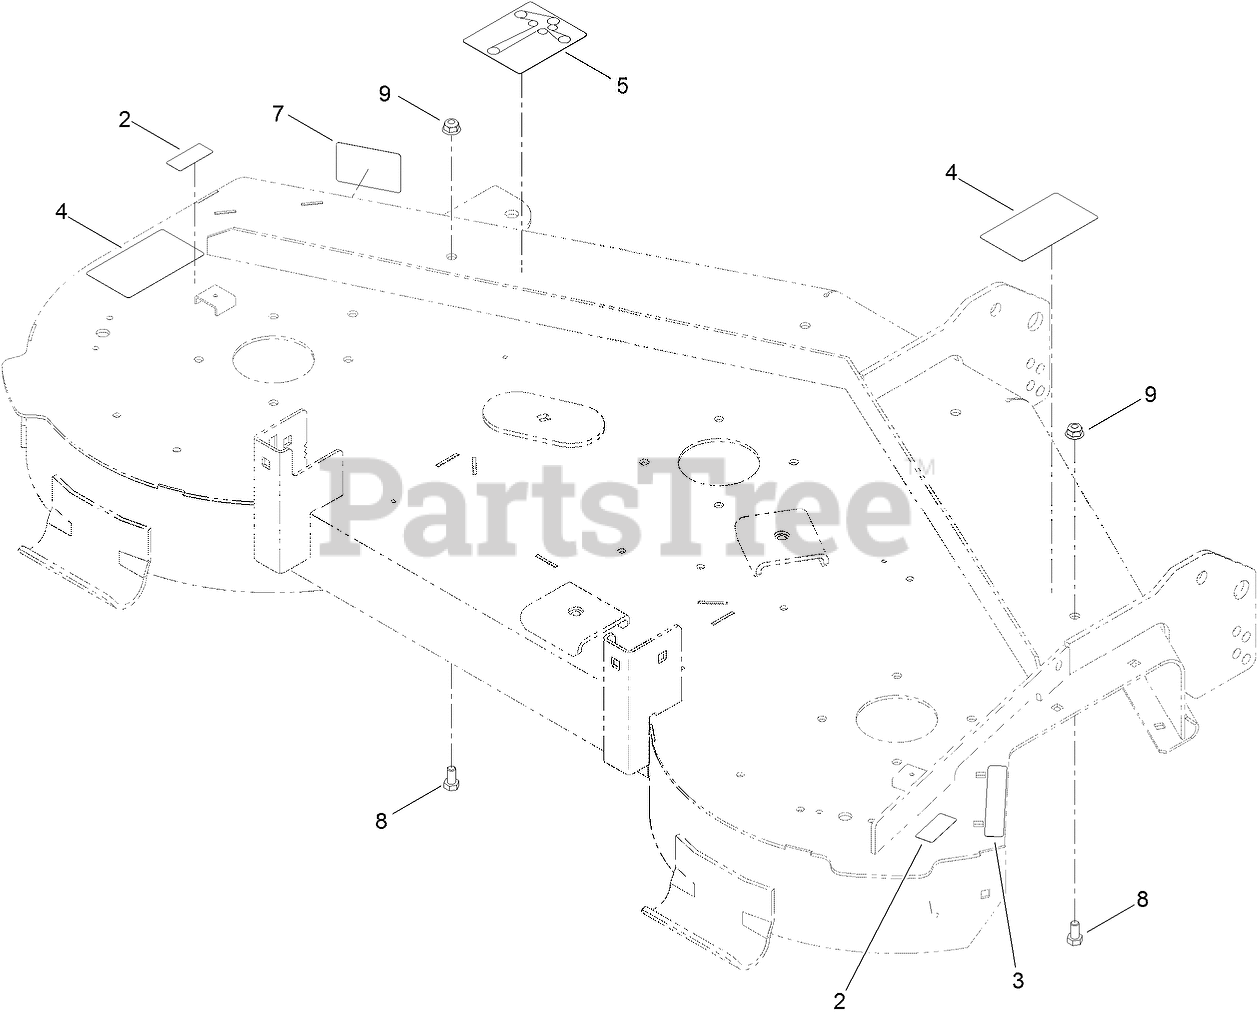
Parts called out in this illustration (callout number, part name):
2	DECAL-DANGER
3	DECAL-DANGER
4	DECAL-DANGER
5	DECAL-ROUTING, BELT
7	DECAL-SCALP, ANTI
8	SCREW-HH
9	NUT-HF, NI
